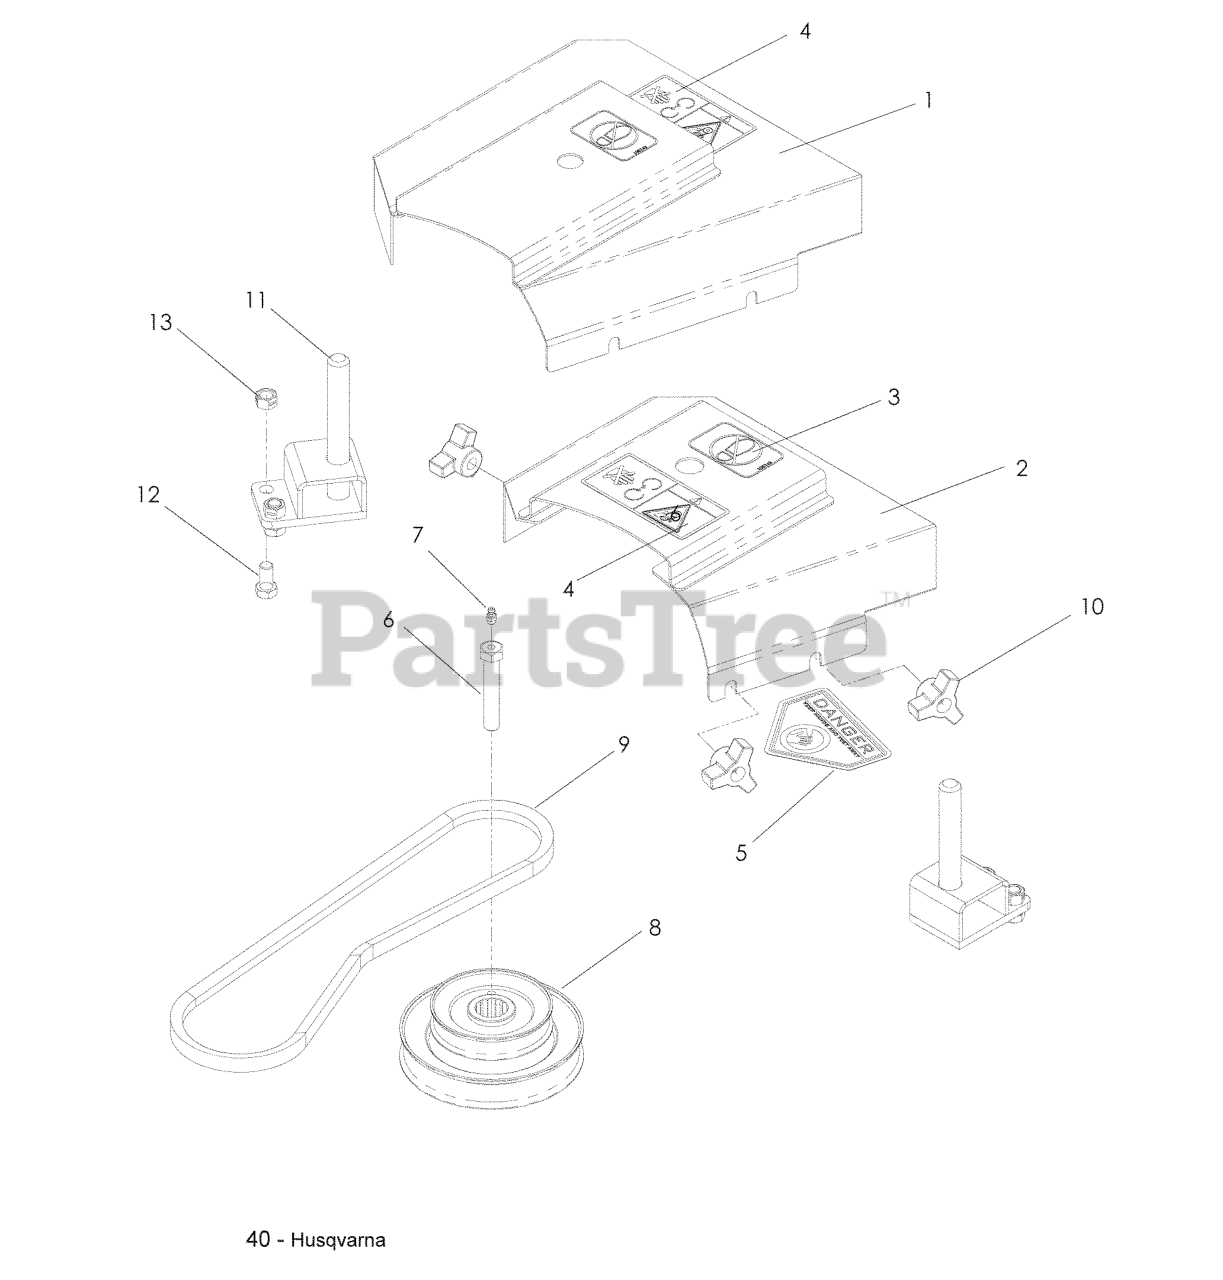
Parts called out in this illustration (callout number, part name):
1	BELT SHIELD W/DECALS, 52
2	BELT SHIELD W/DECALS, 61
3	DECAL, NO STEP
4	DECAL, BELT DRIVE
5	DECAL, CPSC
6	HCS, 7/16-20 X 2 1/2, GR8
7	ZERK
9	V-BELT PUMP DRIVE
10	KNOB, THREE PRONG
11	BLOWER PIN WELDMENT ASM.
12	SCREW 3/8C X 3/4 HEX CAP
13	NUT 3/8C CENTERBLOCK
